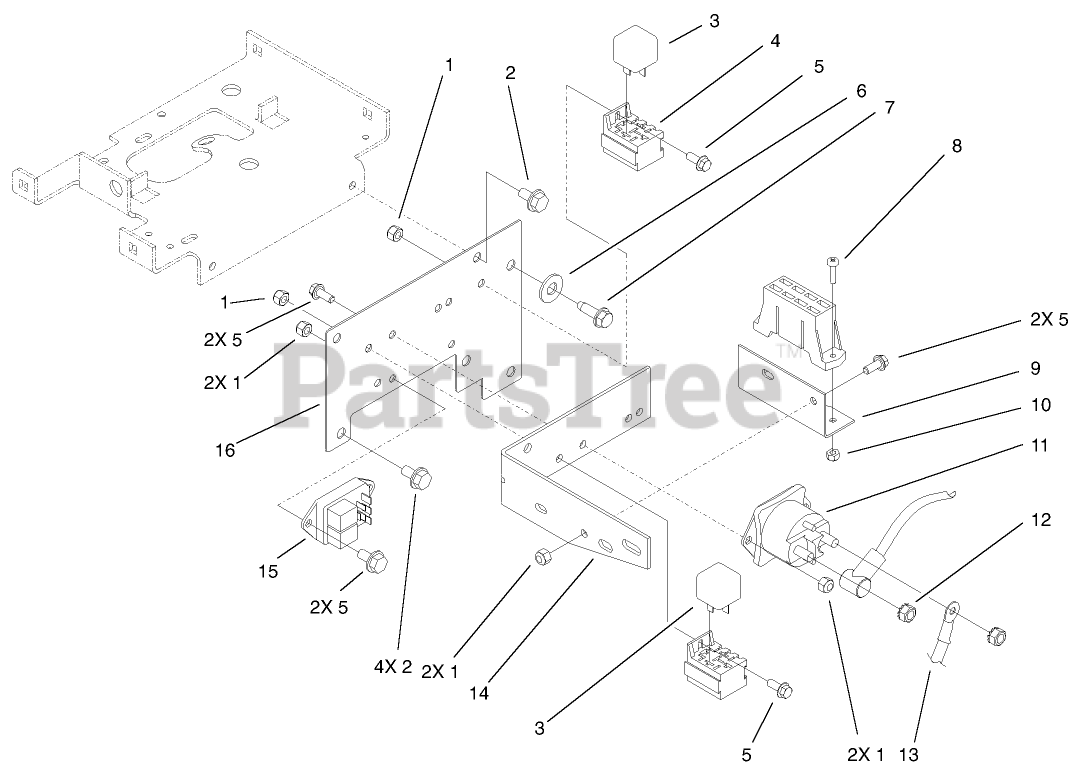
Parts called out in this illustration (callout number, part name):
1	NUT-LOCK, NI
2	SCREW-HWHTF
3	RELAY
4	HARNESS-WIRE
5	SCREW-HHF
6	WASHER-FLAT
8	SCREW-PAN
9	FUSE HOLDER
10	NUT-LOCK, NI
11	SOLENOID
12	NUT-KEPS
13	CABLE-BATTERY, POSITIVE
14	BRACKET-BELT
15	MODULE-CLUTCH
16	PLATE-HOODSTAND, FRONT
